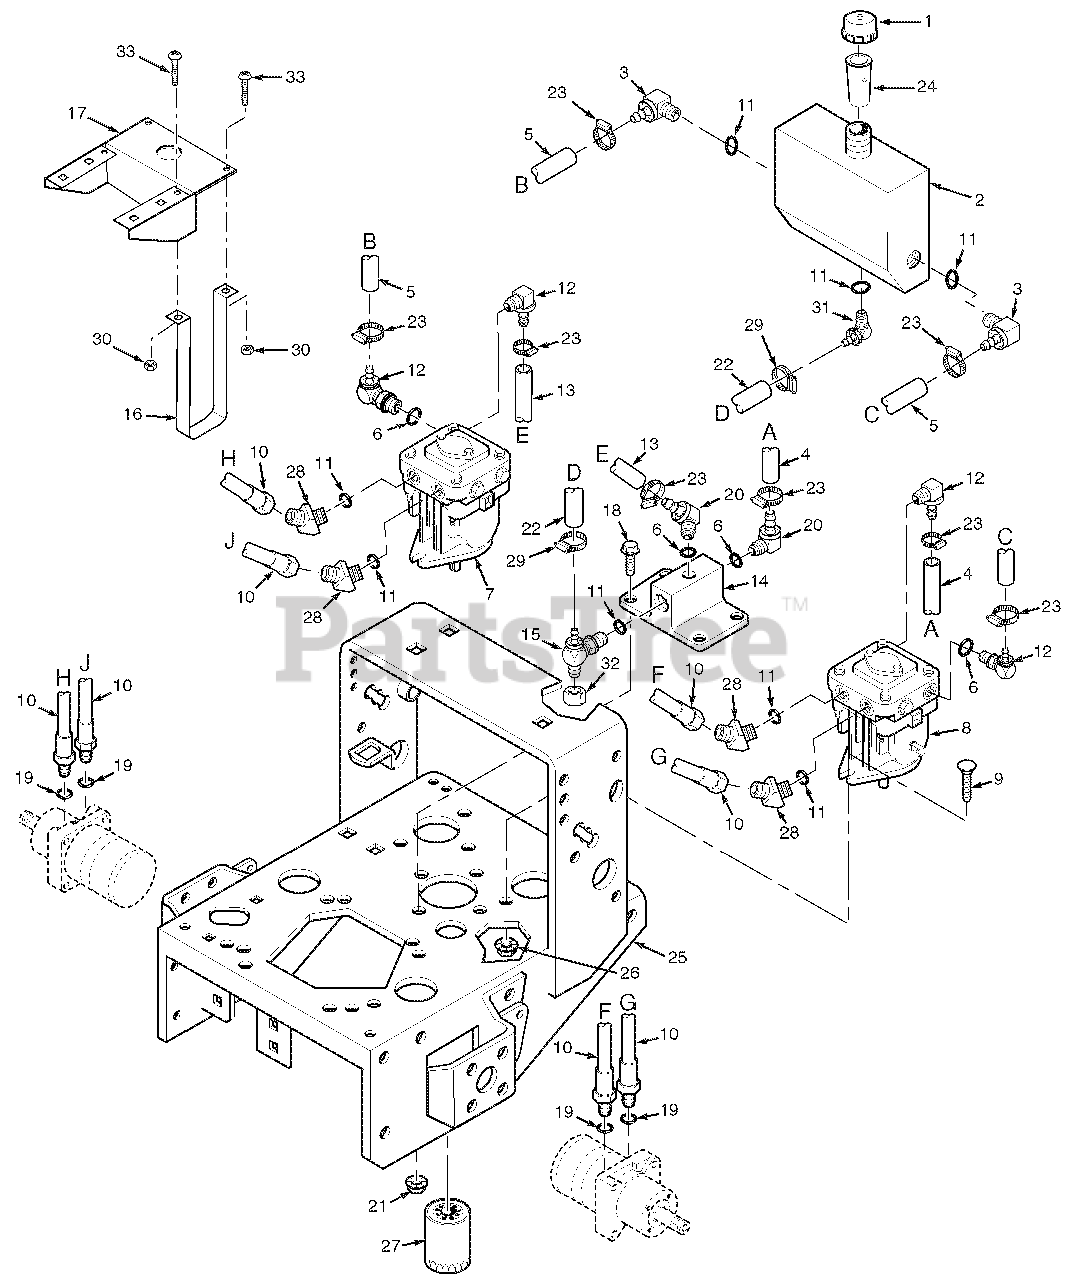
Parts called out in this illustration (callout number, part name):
1	Cap, Oil Reservoir
2	Oil Reservoir
3	Elbow, 9/16 O-Ring x 3/8" Hose
4	Hose, 3/8" ID - 10-1/4" Long
5	Hose, 3/8" ID - 7" Long
6	O-Ring
7	Pump, PG-1JQQ-DY1X-XXXX
8	Pump, PG-1GQQ-DY1X-XXXX
9	Bolt, Carriage, 3/8-16 x 1.25"
10	Hose, Pump to Wheel Motor
11	O-Ring
12	Elbow, 7/16-20 O-Ring x 3/8" Hose
13	Hose, 3/8" ID - 11" Long
14	Oil Filter Base
15	Tee, 3/8 O-Ring x JIC x 1/2" Hose
16	Strap, Hydraulic Tank
17	Bracket, Hydraulic Tank
18	Capscrew, 5/16-18 x .75" Serr. Flange
19	O-Ring
20	Elbow, 9/16 O-Ring x 3/8" Hose
21	Nut, 5/16-18 Serr. Flange
22	Hose, Formed 1/2" ID
23	Clamp, .69 max dia.
24	Tube, Filler Neck
25	Engine Deck W/Decals
26	Nut, 3/8-16 Serr. Flange
27	Oil Filter
28	Elbow, 45 Deg.-3/4-16 JIC Male x Male 3/4-16 O-Ring
29	Clamp, .87 max dia.
30	Nut, 1/4-20
31	Elbow, 3/4-16 O-Ring x 1/2" Hose
32	Cap, 3/4-16
33	Screw, 1/4-20 x 2" Round Head Phillips
